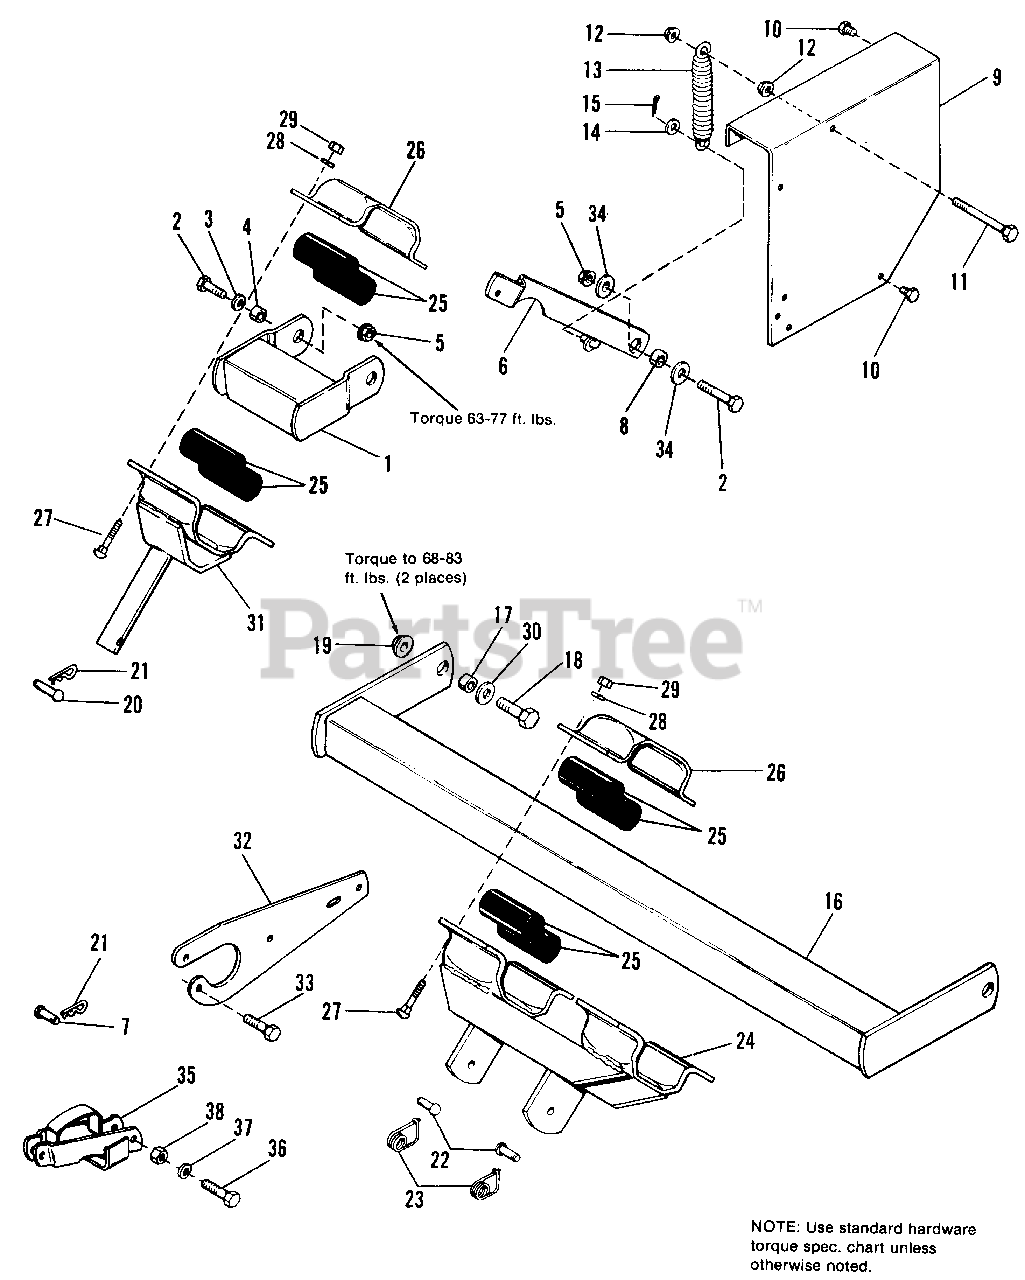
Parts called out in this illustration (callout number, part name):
1	YOKE ASSY., Lift
2	CAPSCREW, Hex Hd., 7/16-14 x 1-1/4
3	WASHER, 3/8
5	LOCKNUT, Flange, 7/16-14
6	ARM ASSY., Pivot
9	SHIELD, Pulley
10	SCREW, Hex Hd., Taptite, 5/16-18 x 3/8
11	CAPSCREW, Hex Hd., 3/8-16 x 4-1/4
12	LOCKNUT, Flange, 3/8-16
14	WASHER, 1/4
15	COTTER PIN, 3/32 x 1
16	HITCH ASSY., Tiller Half
18	CAPSCREW, Hex Hd., 1/2-13 x 1-1/2
19	LOCKNUT, Flange, 1/2-13
20	PIN
21	CLIP, Spring
23	CLIP, Spring, Safety
24	HITCH ASSY., Tractor Half
27	CARRIAGE BOLT, 3/8-16 x 1-1/2
28	LOCKWASHER, 3/8
29	NUT, Hex, Full, 3/8-16
30	WASHER, Plain, 1/2
31	BAR ASSY., Lift
32	BRACE, Transmission
33	CAPSCREW, Hex Hd., 7/16-14 x 1-1/4
35	ARM ASSY., Lift
36	CAPSCREW, Hex Head 5/16-18 x 2 G5
37	LOCKWASHER, 5/16
38	NUT, Hex, Full, 5/16-18
